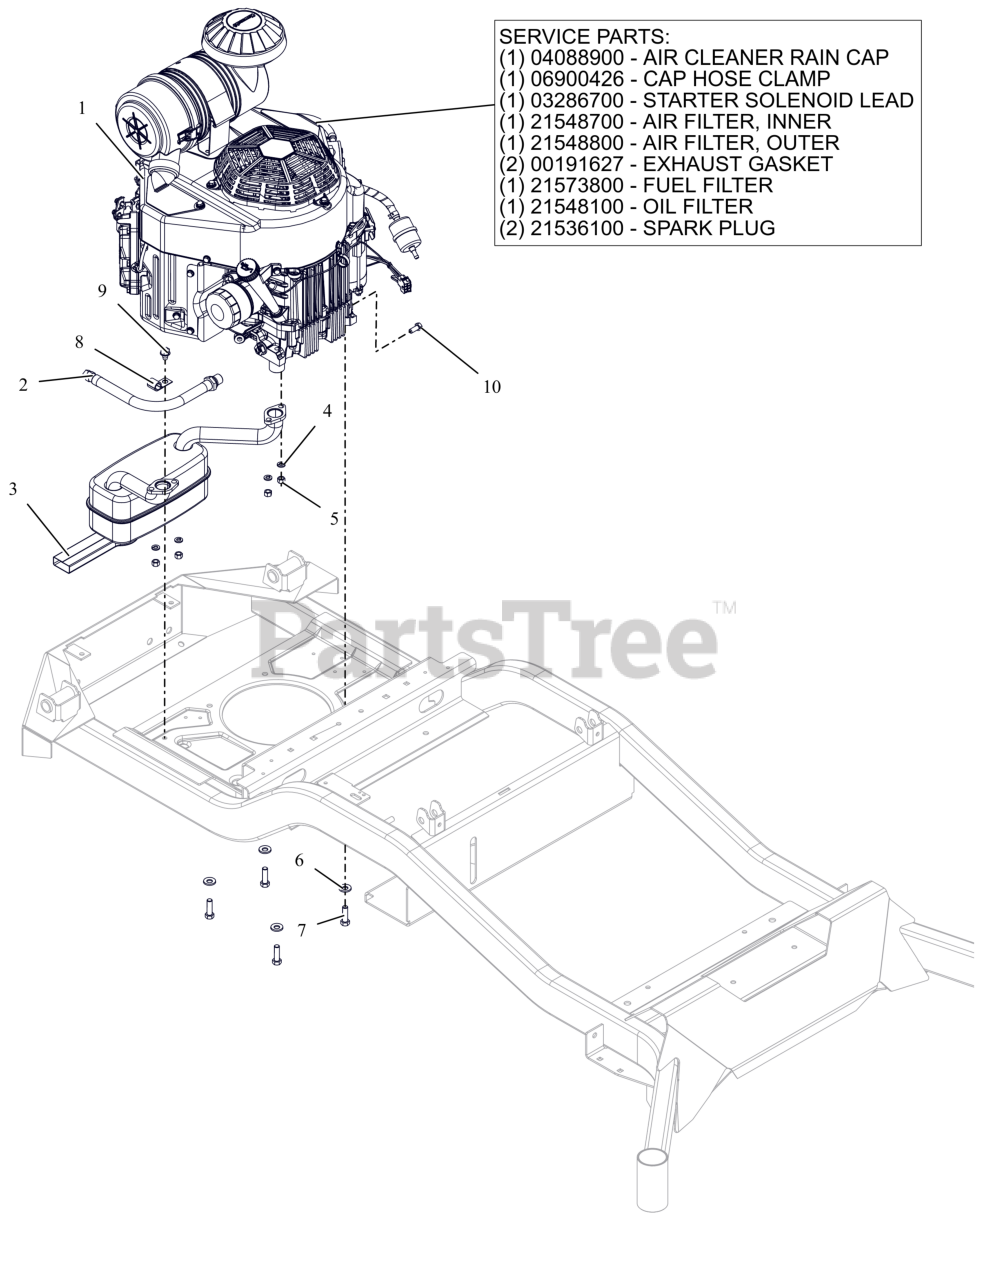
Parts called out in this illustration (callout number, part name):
1	ENGINE, KAWASAKI FX730
1	CAP, KAW 11065-7025
1	CLAMP, HOSE #36 SS 1.813-2.75
1	LEAD - STARTER SOLENOID
1	FILTER, INNER - KAW
1	FILTER, OUTER
1	GASKET, MUFFLER S/O
1	FUEL FILTER-KAWASAKI FR
1	OIL FILTER, KAWASAKI FR
1	PLUG, SPARK
2	HOSE, OIL DRAIN
3	MUFFLER, KAWASAKI
4	WSHR,LK-REG .312X.078 ZCC
5	NUT-LK-TOP-FLG M8 ZCC
6	WASHER, 3/8" SPRING DISC
7	BLT, HEX .38-16X1.25 G5 ZCC NT
8	J-CLAMP
9	SCR,TAP .375-16X.50 HWH TR ZCC
10	BLT, HEX M8-1.25X20 G8.8 ZCC
